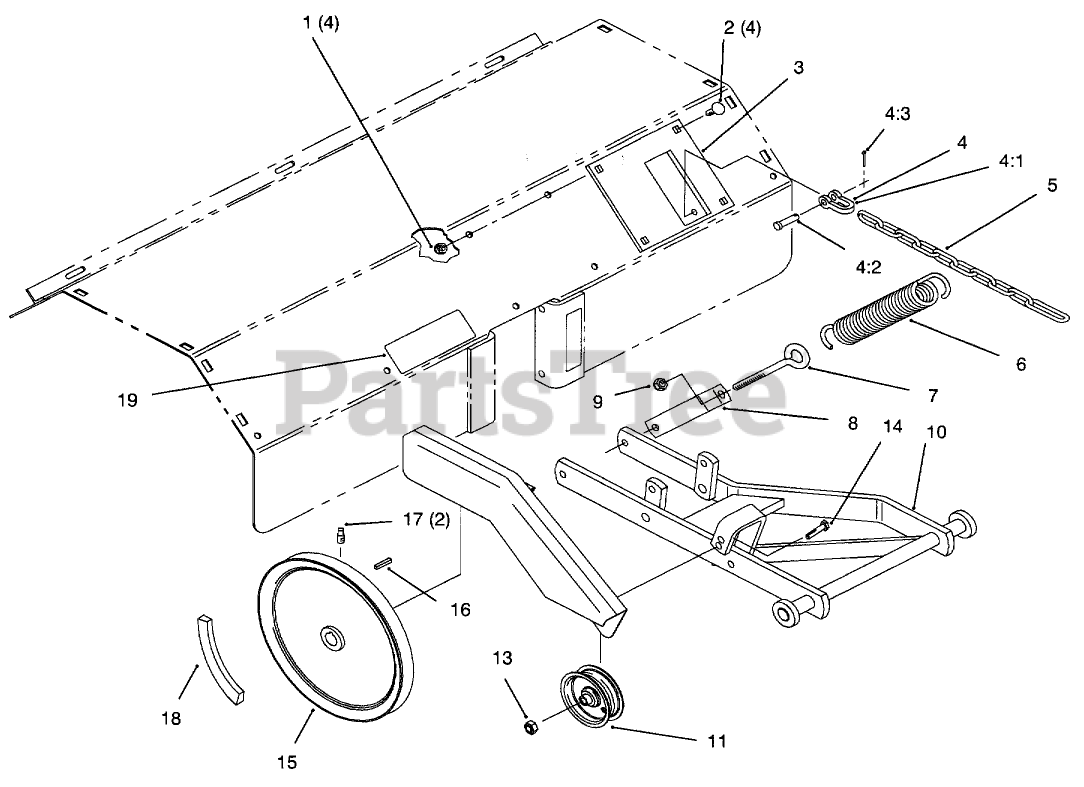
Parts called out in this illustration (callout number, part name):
1	NUT-LOCK, NI
2	BOLT-CARR
3	HITCH ASM
4	Clevis & Pins Asm (Incl. Ref.,4:1,4:2,4:3)
4:1	Clevis
4:2	Pin-Clevis
4:3	Pin-Cotter
5	CHAIN LIFT
6	SPRING
7	EYEBOLT
8	BRACKET - SPRING RED
9	NUT-LOCK, NI
10	Hitch
11	PULLEY-IDLER
13	NUT-HEX
15	PULLEY
16	KEY-STRAIGHT
17	SCREW-SQH
18	V-BELT
